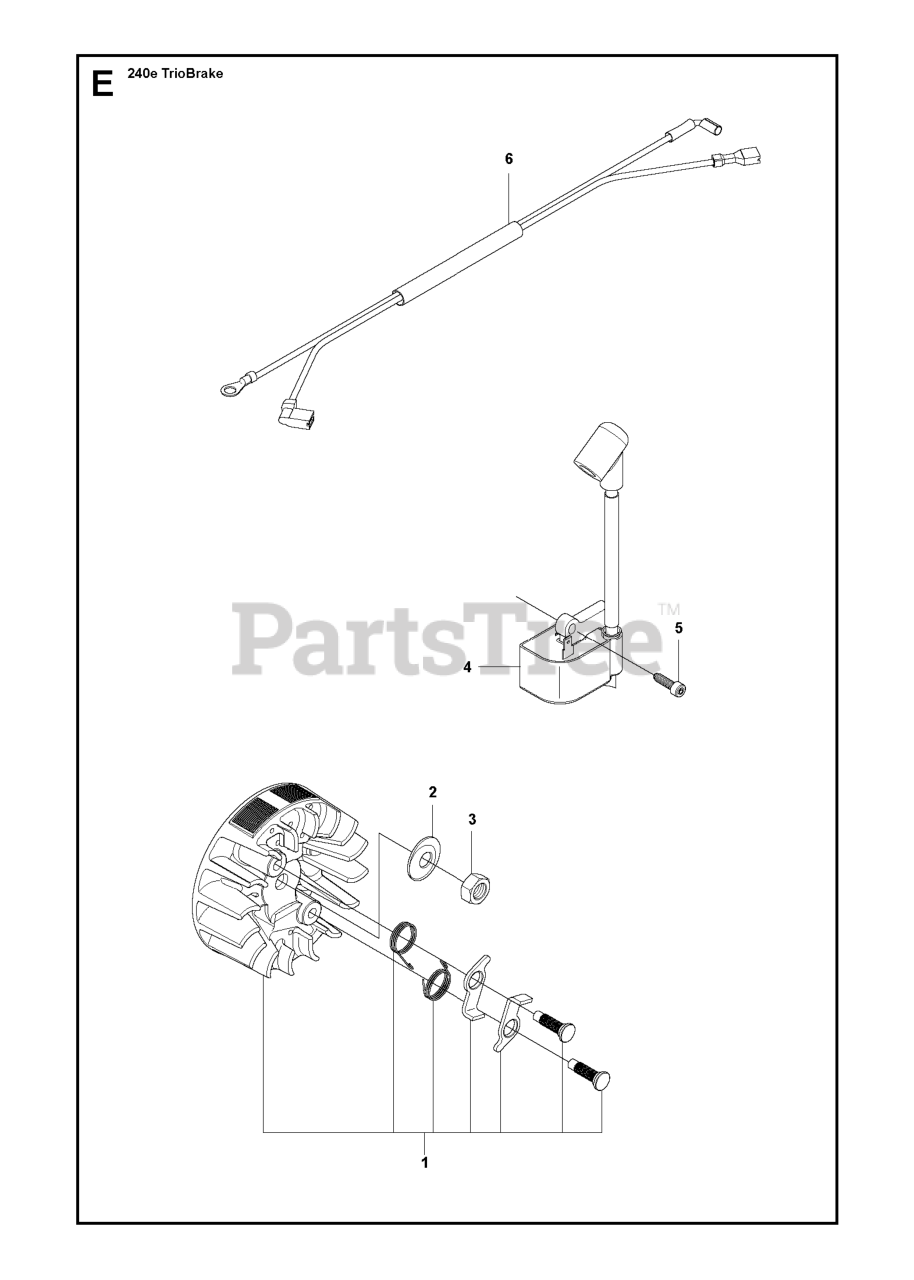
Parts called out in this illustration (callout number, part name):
1	ROTOR COMPL. 36/41
2	WASHER-FLYWHEEL
3	NUT-FLYWHEEL
4	IGNITION MODULE
6	WIRE HARNESS ASSY
